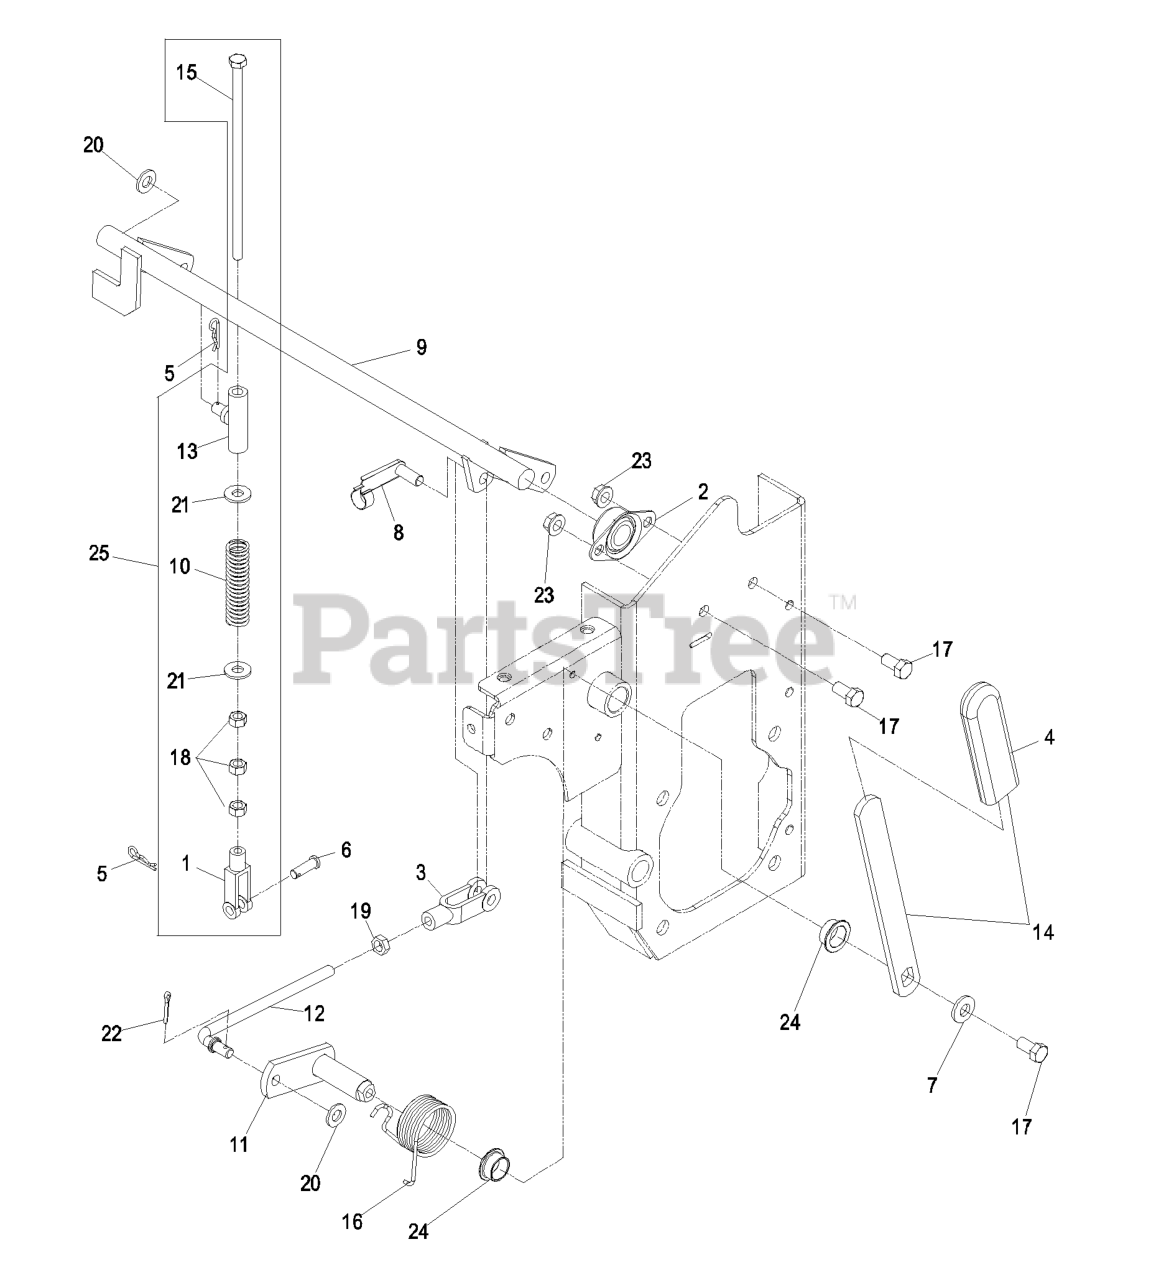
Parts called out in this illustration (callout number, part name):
1	YOKE-ADJUSTABLE
2	BEARING-FLANGE, SIDE
3	YOKE-LINKAGE, BRAKE
4	GRIP-LEVER
5	PIN-COTTER
6	PIN-CLEVIS
7	WASHER-BELLEVILLE
8	PIN-SPRING, CLEVIS
9	WLD, BRAKESHAFT
10	SPRING,COMPRESSION
11	WLD,BRAKE PIVOT (PLATED)
12	ROD,LINKAGE BRAKE (PLATED
13	WLD,SWIVEL BRAKE (PLATED)
14	PARK BRAKE HANDLE ASM
15	SCREW-HH
16	SPRING,TORSION RH
17	SCREW-HH
18	NUT-HEX
19	NUT-HEX
20	WASHER-FLAT
21	WASHER-FLAT
22	PIN-COTTER
23	NUT-HHF, WHIZ
24	BUSHING-BRONZE
25	ASM,BRAKE LINKAGE
